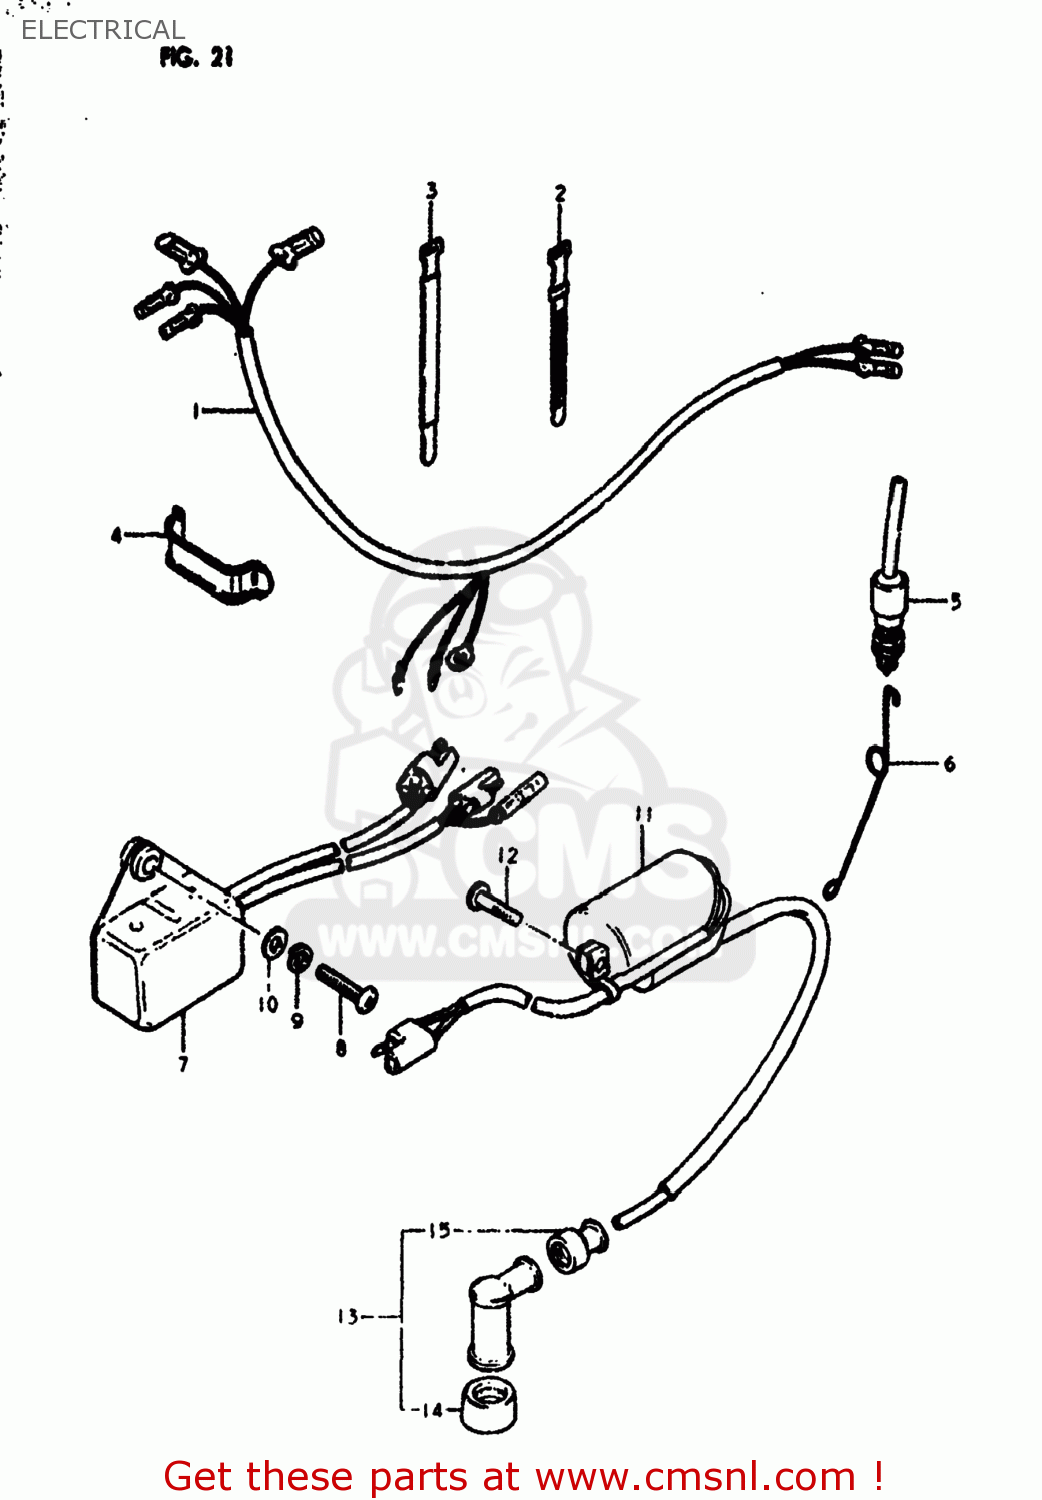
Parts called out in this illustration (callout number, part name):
1	HARNESS,WIRING
2	CLAMP(L:120)
3	CLAMP
4	CLAMP
5	SWITCH ASSY, STOP LAMP
6	SPRING
7	CDI UNIT
8	SCREW
9	LOCK WASHER
10	WASHER
11	COIL ASSEMBLY,IGNITION
12	SCREW 5X20
13	CAP,SPARK PLUG
14	SEAL,SPARK PLUG
15	SEAL,SPARK PLU
